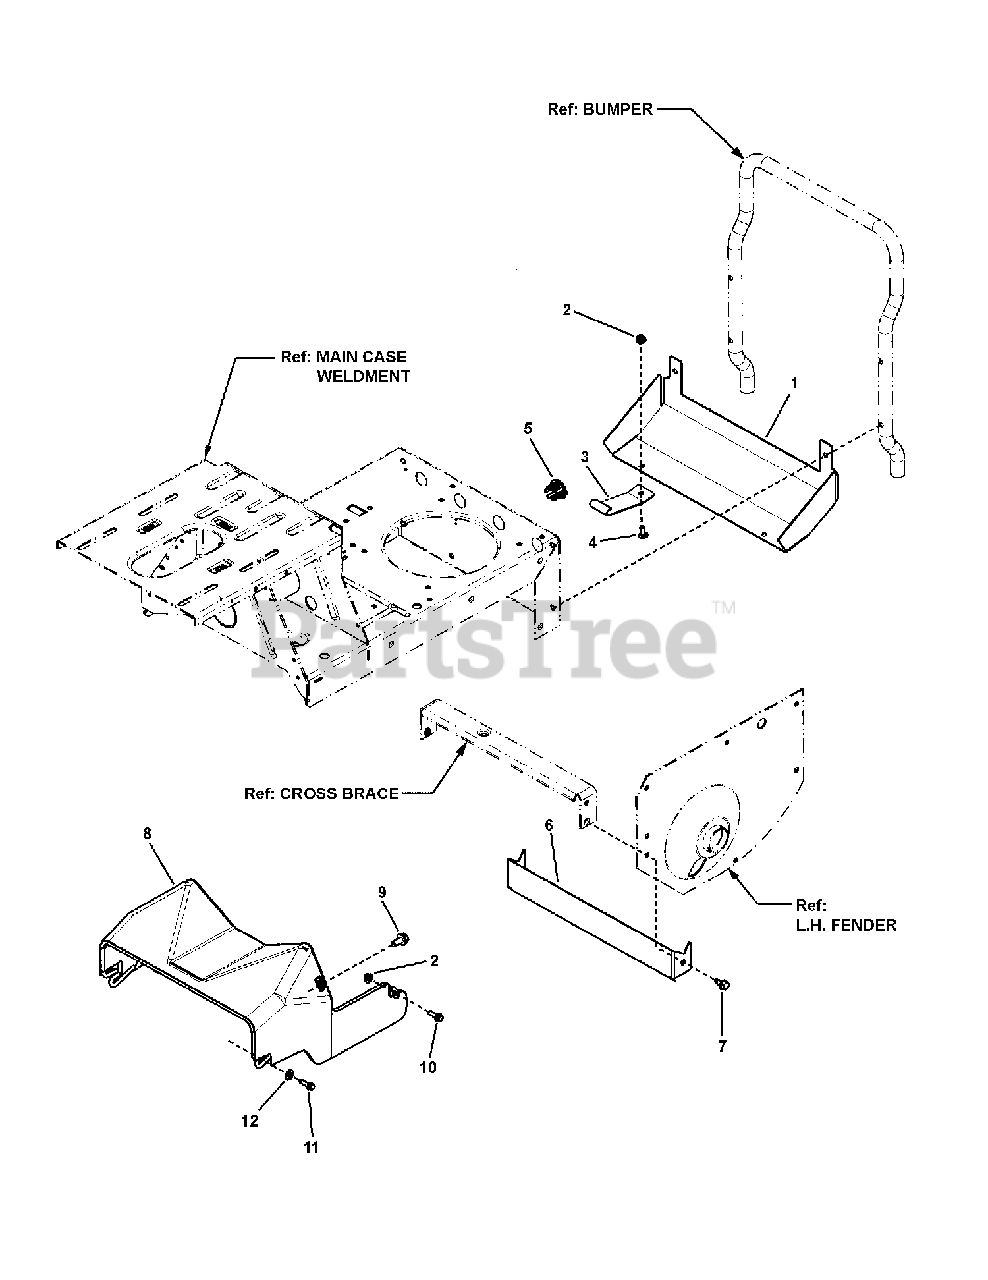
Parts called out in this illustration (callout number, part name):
1	REAR GUARD, Euro Maincase
2	NUT, 1/4-20, GR5, Ser. Flng, Zinc/Clear
3	STRAP, Rear Guard
4	BOLT, 1/4-20 X .750, Carriage, Zinc/Clear
5	PLUG, 1 Hole
6	GUARD, Main Case, Front, Euro RER
7	SCREW, 5/16-18 x 5/8 Hex Washer Self-Tap
8	GUARD ASSEMBLY, Wire Form (Euro)
9	SCREW, 3/8-16 x 3/4 Hex Washer Self-Tap, BZ
10	SCREW, 1/4-20 x 3/4 Hex Head Flange, GR 5, YZ
11	SCREW, 1/4-20 x 1 Hex Washer Self-Tap
12	WASHER, 11/32 Flat
